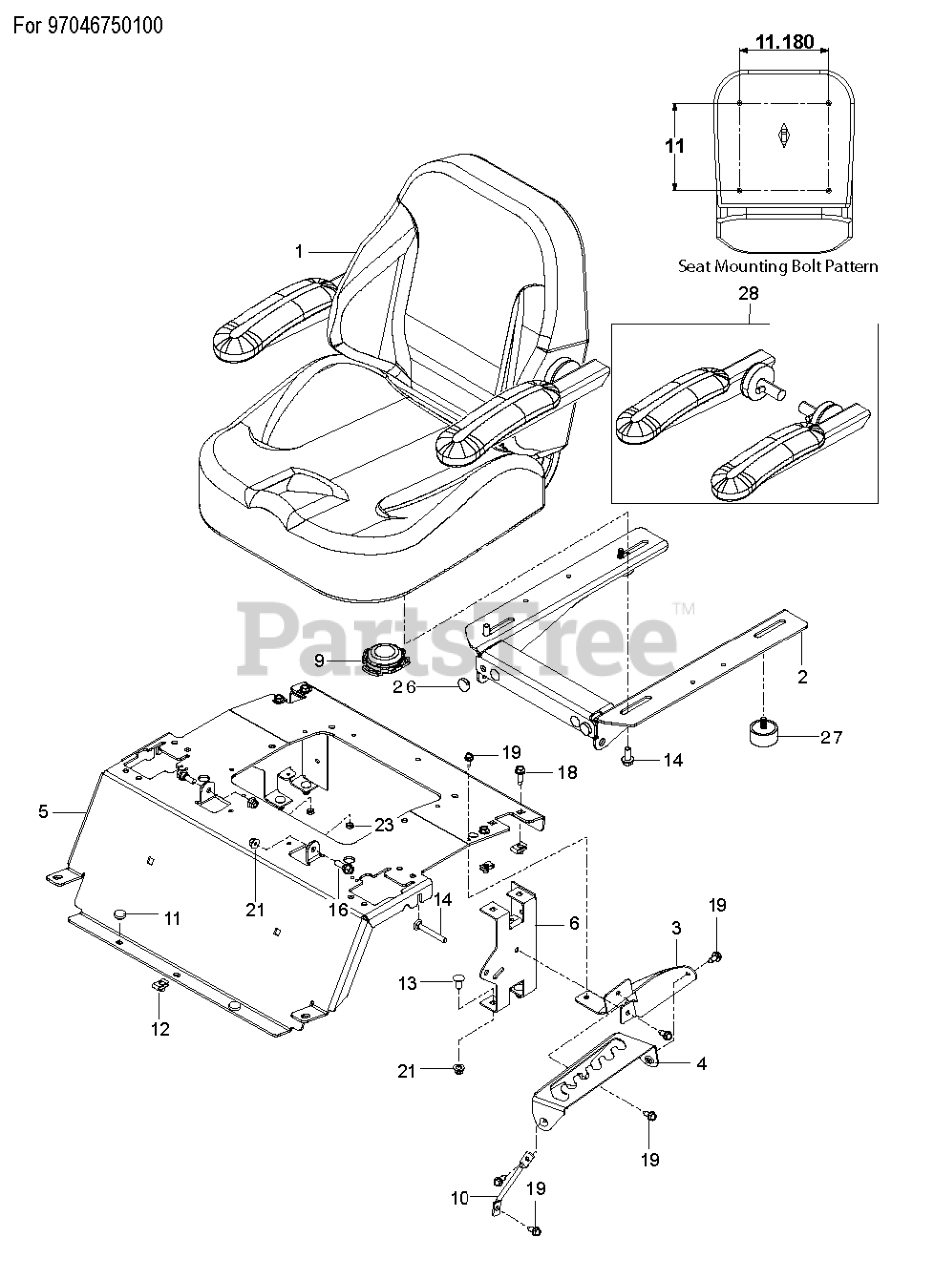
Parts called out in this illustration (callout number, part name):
3	PLATE.SUPPORT.DECK.LIFT.X431
4	PLATE.DECK.LIFT.X431
5	SUPPORT.SEAT.RZ.HUSQ.ORANGE
6	SUPPORT REAR SEAT BLACK
9	SWITCH.SEAT.DELTA.OPC.
10	SUPPORT.LEG.DECK.LIFT
11	WASHER
12	U-CLIP 5/16-18 NUT RETAINER
13	BOLT 5/16C X 3/4" CARRIAGE
16	BOLT, SHOULDER
18	SCREW.THDROL.5/16-18X3/4.TTY
19	BOLT.5/16HEX.WHS.HD
21	5/16-18 NYLOC FLANGE NUT
23	NUT
26	GROMMET, BUMPER
27	BUMPER 5/16-18 CLEAR ZINC
28	SEAT KING 18" WOOD BTM, ARM
